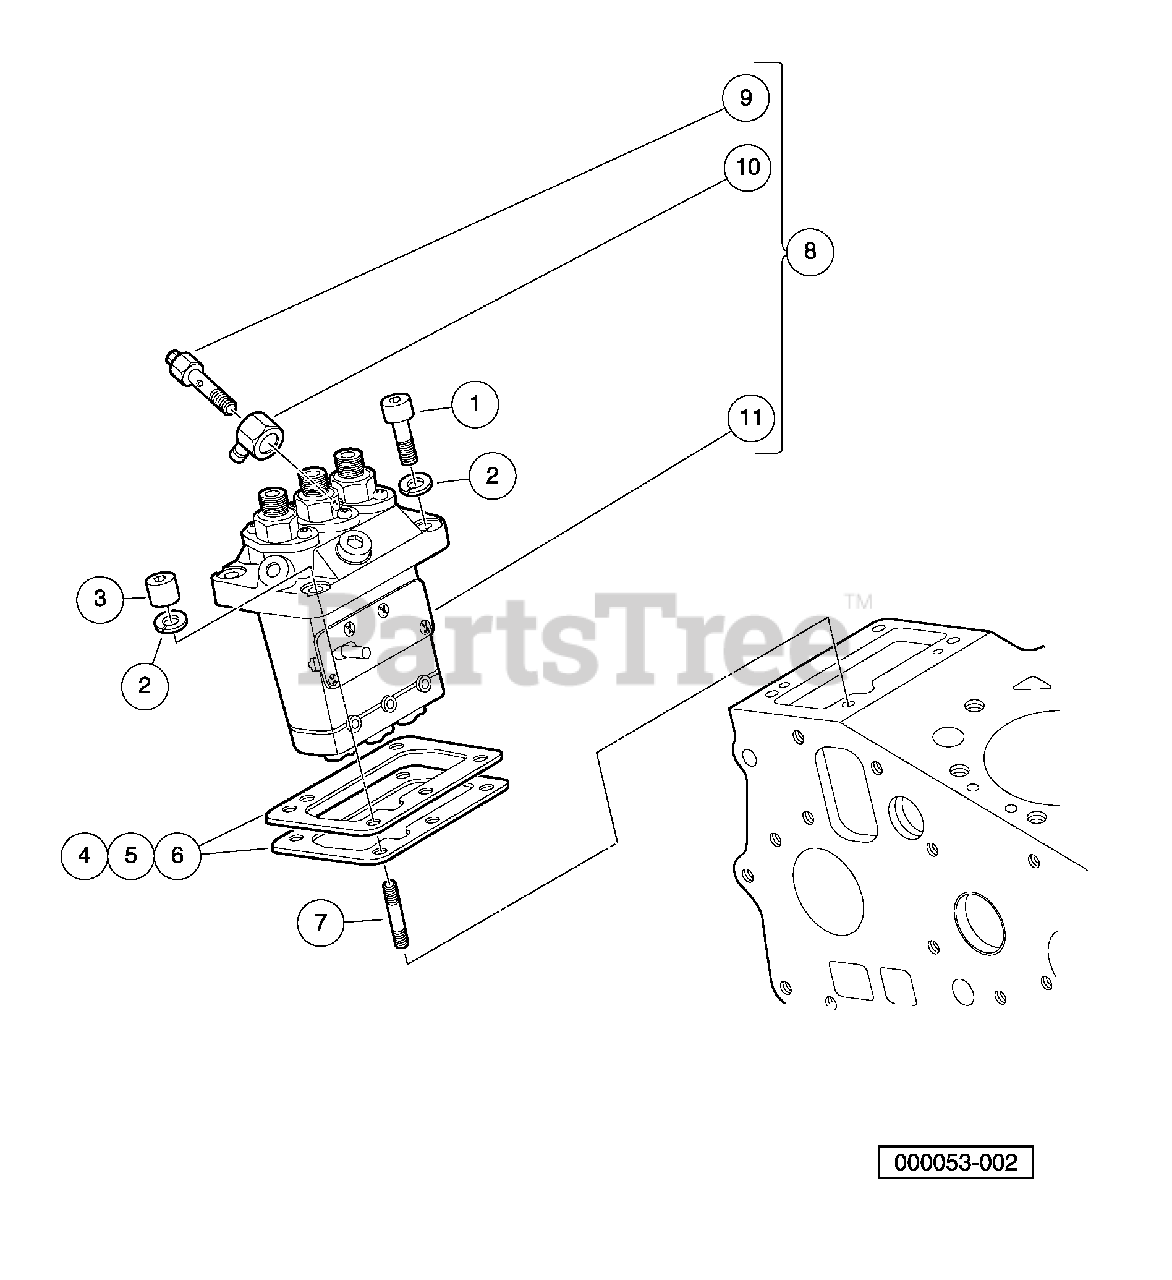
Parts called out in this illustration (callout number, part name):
1	Bolt, Hex-Head, M5 X 0.75 X
2	Washer, Spring, M6, D722
3	Nut, Special
4	Shim, Injection Pump, 0.20 mm
5	Shim, Injection Pump, 0.25 mm
6	Shim, Injection Pump, 0.30 mm
7	Stud, M5 X 25
8	Assembly, Fuel Injection Pump
9	Screw, Hollow, D722, Inj Pump
10	Joint, Eye
11	Pump, Injection
